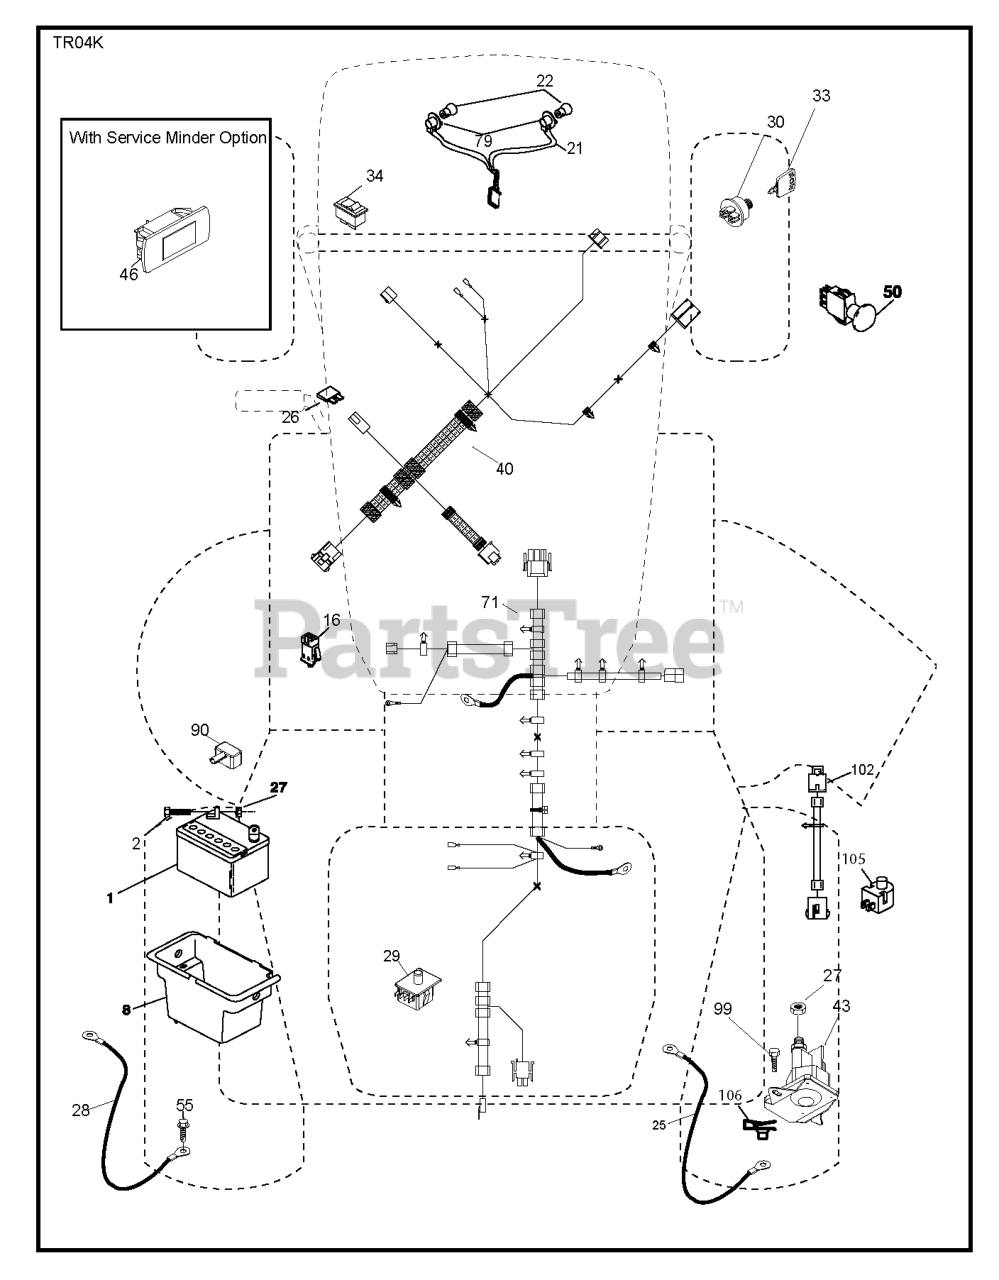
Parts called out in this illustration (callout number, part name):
1	Battery 12 Volt 25 Amp
2	BOLT.HEX.1/4.X.3/4.DICHROMATE
8	BOX.BATTERY.MNT.REAR.L
16	SWITCH INTERLOOK PUSH-IN
21	HARNESS.LIGHT W/4152J BULBS
25	CABLE.BATT.RED.8GA.17
26	FUSE 20AMP
27	NUT
28	CABLE.GROUND.REAR.BATTERY.8G
29	SWITCH.SEAT.DELTA.OPC.
30	SWITCH.IGN.DELTA.W.LGH.ROS
33	KEY.CHAIN.BLISTER.PACK.GEN.USA
40	HARNESS.TEX.DASH.ELEC.REAR BAT
43	SOLENOID.W/BRASS.PLUNGER
46	RP.GUAGE.SRVCMNDR.HRMTR.
50	RP.PTO.SWITCH.8 TERMINAL.BLACK
55	SCREW 5/16"
71	HARNESS.TEX.CHSSIS.REAR.BATT
79	BULB HOLDER ASM.
90	COVER.TERMINAL.BATTERY
99	SCREW HEXWSHR 1/4-20X3/4
102	HARNESS PIGTAIL PCH TEX ROS
105	REVERSE SWITCH
106	1/4-20 U NUT
